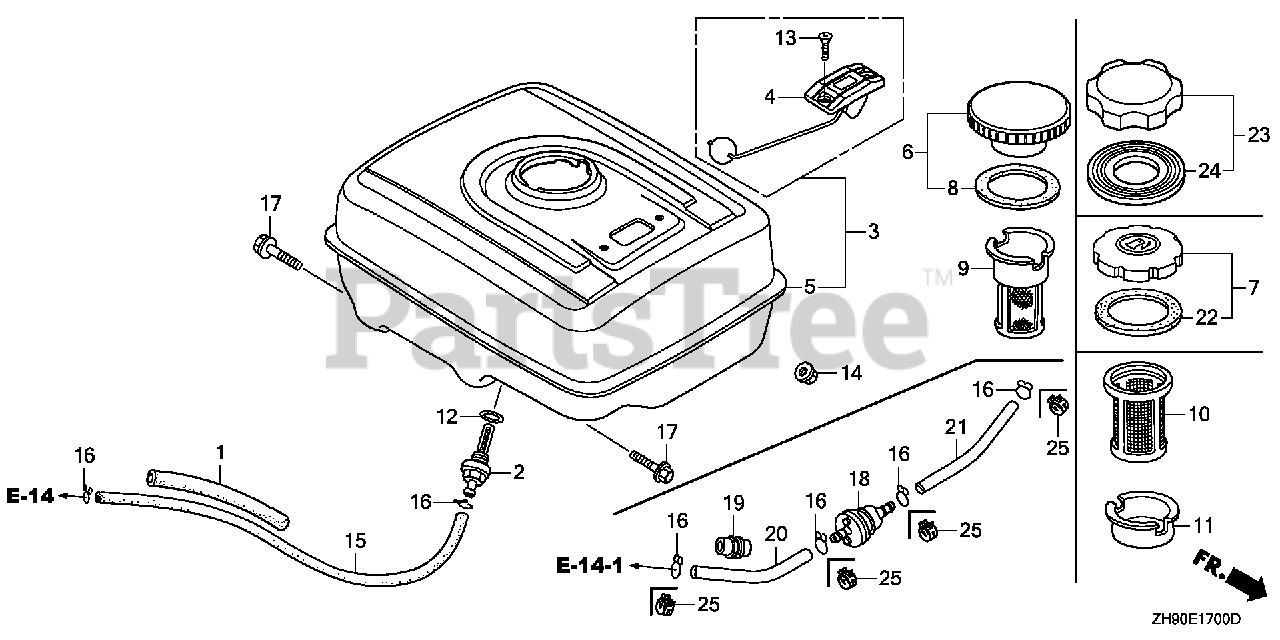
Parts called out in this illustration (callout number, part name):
1	RUBBER, SUPPORTER (107MM)
2	JOINT, FUEL TANK (NOT AVAILABLE)
5	TANK, FUEL *NH1* (BLACK)
9	FILTER, FUEL
12	O-RING (14MM) (ARAI) Use up to Engine SN 2949254.
12	O-RING (14MM) (NOK)
14	NUT, FLANGE (8MM)
15	BULK HOSE, FUEL (4.5X3000) (Honda Code 5137104). (4.5X140)
16	CLIP, TUBE (B8)
17	BOLT, FLANGE (8X25)
23	CAP, FUEL FILLER (CHROME PLATED)
24	GASKET, FUEL FILLER CAP (39X62X3) (TOUYOUSYA)
